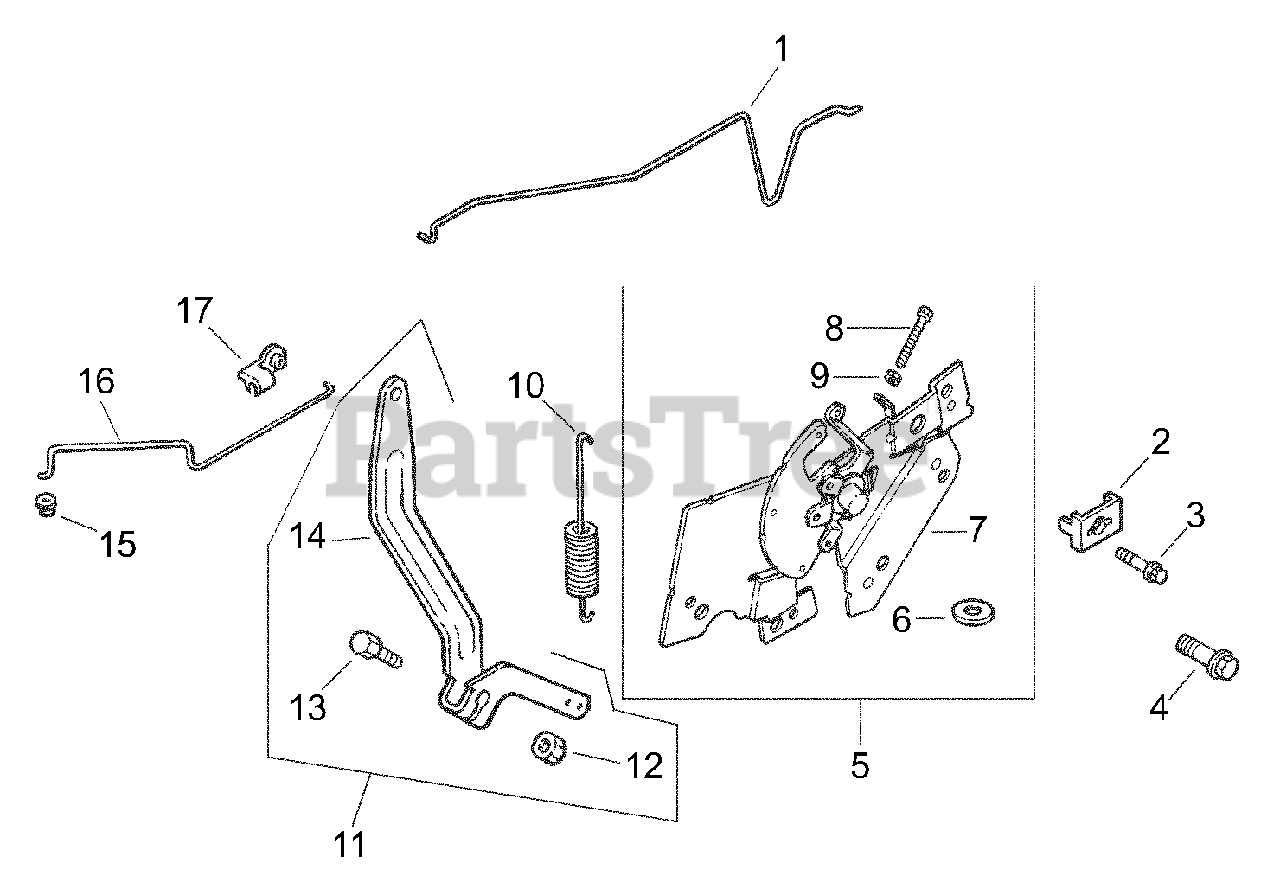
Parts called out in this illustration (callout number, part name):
1	Linkage, Choke
2	Clamp, Cable
3	Screw, Hex. Flange M5 x 0.8 x 16
4	Screw, Lobed Socket M6 x 1.0 x 20
5	Control, Speed Assembly
6	Spacer, Shim .005
7	Bracket, Control
8	Screw, Hex. Flange M4 x 0.7 x 30
9	Nut, Hex. M4 x 0.7
10	Spring, Governor
11	Kit, Governor Lever
12	Nut, Hex. Flange M6 x 1.0
13	Screw, Hex. Flange M6 x 1.0 x 25
14	Lever, Governor
15	Bushing, Linkage Retaining
16	Linkage, Throttle
17	Bushing, Linkage Retaining
